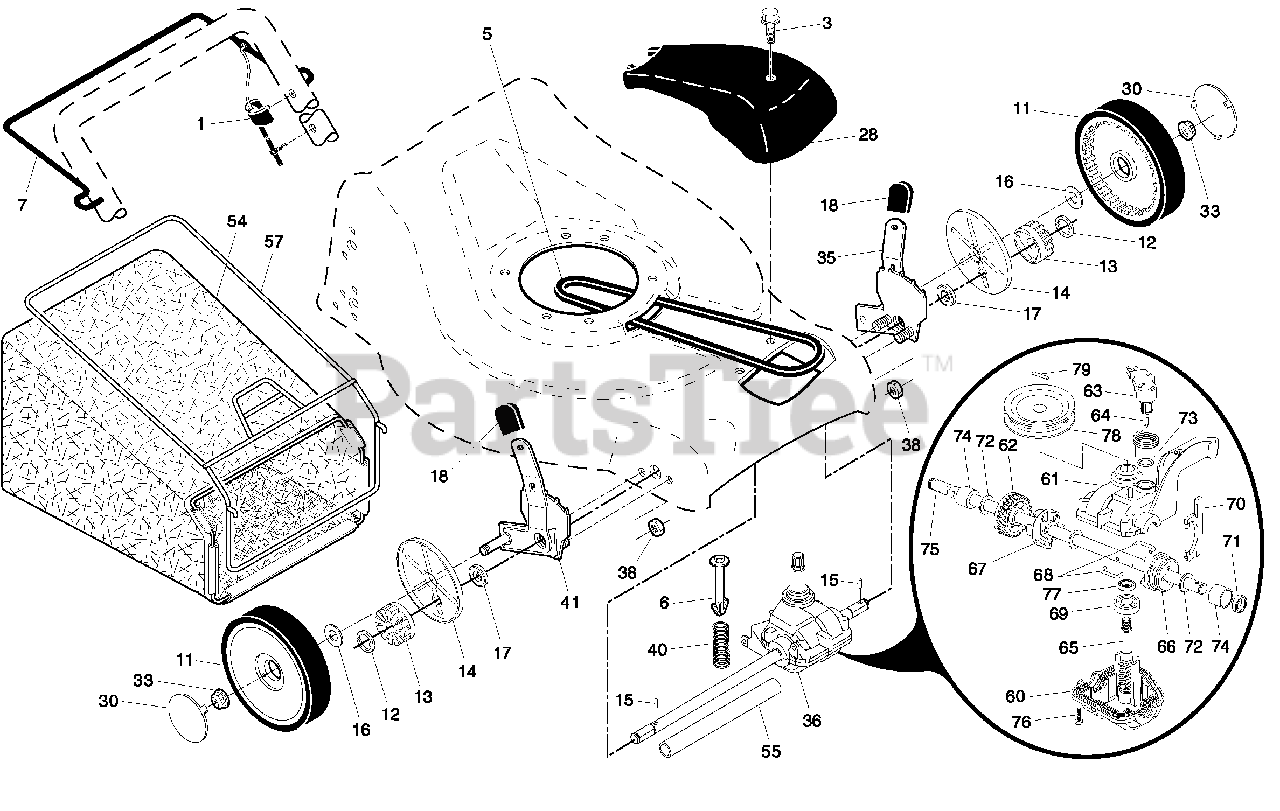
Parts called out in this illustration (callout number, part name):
1	Drive Control Assembly
3	Pan Head Tapping Screw #10-24 x 2-3/4
5	V-Belt
6	Retainer, Spring
7	Bar, Drive Control
11	Wheel & Tire Assembly, Front, 8"
12	E-Ring
13	Pinion, Gear
14	Dust Cover
15	Pawl, Drive
16	Washer 1/2 x 1-1/2 x .134
17	Bearing, Wheel Adjuster
18	Selector Knob
28	Drive Cover
30	Hubcap
33	Locknut
35	Kit, Wheel Adjuster, LH
36	Gear Case Assembly, Complete
38	Locknut 1/4-20
40	Spring
41	Kit, Wheel Adjuster, RH
54	Grassbag Assembly
55	Driveshaft Cover
57	Frame, Grassbag
60	Case, Lower
61	Case, Upper
62	Gear, 27 Teeth
63	Lever, Clutch
64	Spring, Return
65	Shaft, Input
66	Dog, Movable
67	Dog, Fixed
68	Wire, Formed
69	Bearing, Ball
70	Fork, Shift
71	Seal, Output Shaft
72	Washer
73	Seal, Case
74	Bushing
75	Shaft, Output
76	Screw
77	Seal, Input Shaft
78	Drive Pulley
79	Pin, Retainer
